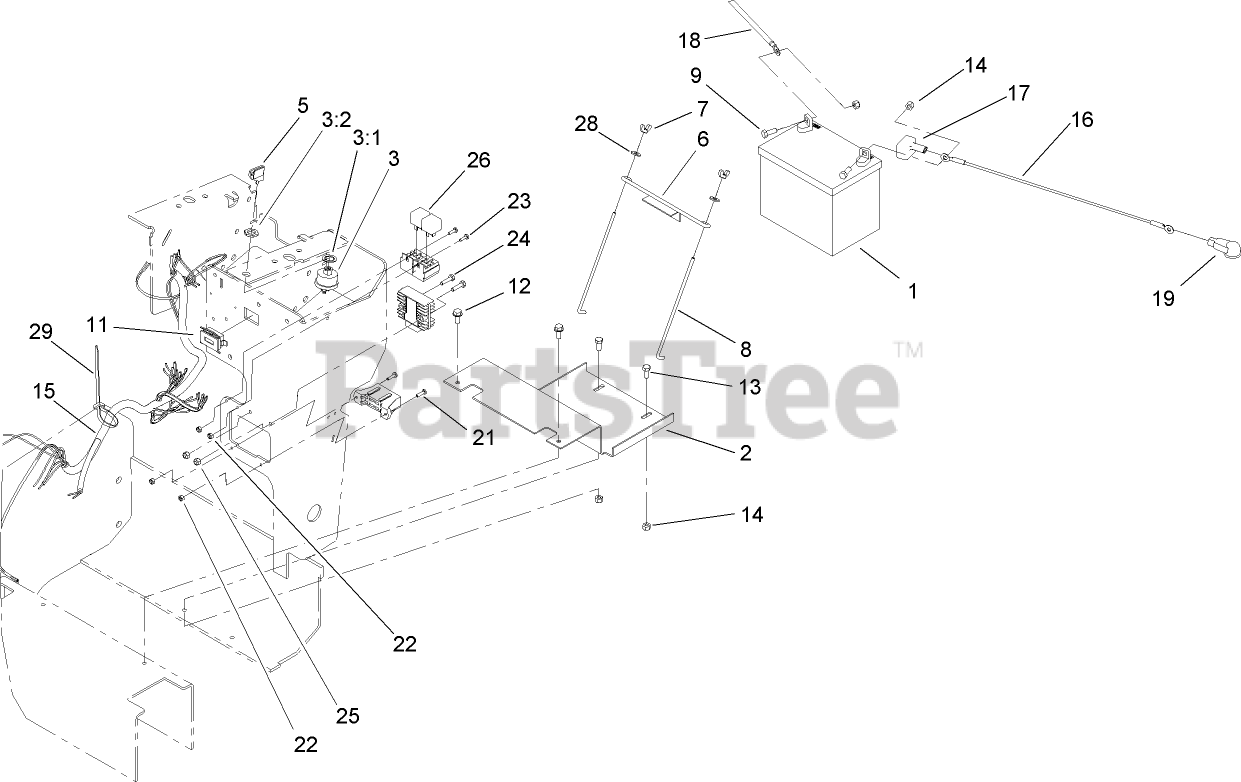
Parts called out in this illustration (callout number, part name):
1	BATTERY-DRY
2	BRACKET-BATTERY
3	Key Switch ASM
3:1	WASHER-TOOTH, INTERNAL
3:2	NUT-HH
5	KEY-IGNITION
6	HOLDDOWN-BATTERY
7	NUT-WING
8	RETAINER-BATTERY
9	SCREW-HH
11	HOURMETER
12	SCREW-HWHTF
13	SCREW-HH
14	NUT-LOCK, NI
15	HARNESS-WIRE
16	CABLE-POSITIVE
17	BOOT-TERMINAL
18	CABLE-BATTERY, NEGATIVE
19	BOOT-INSULATOR, TERMINAL
21	SCREW-PPH
22	NUT-LOCK, NI
23	SCREW-PPH
24	SCREW-HH
25	NUT-LOCK, NI
26	RELAY
28	WASHER-FLAT
29	TIE-CABLE
